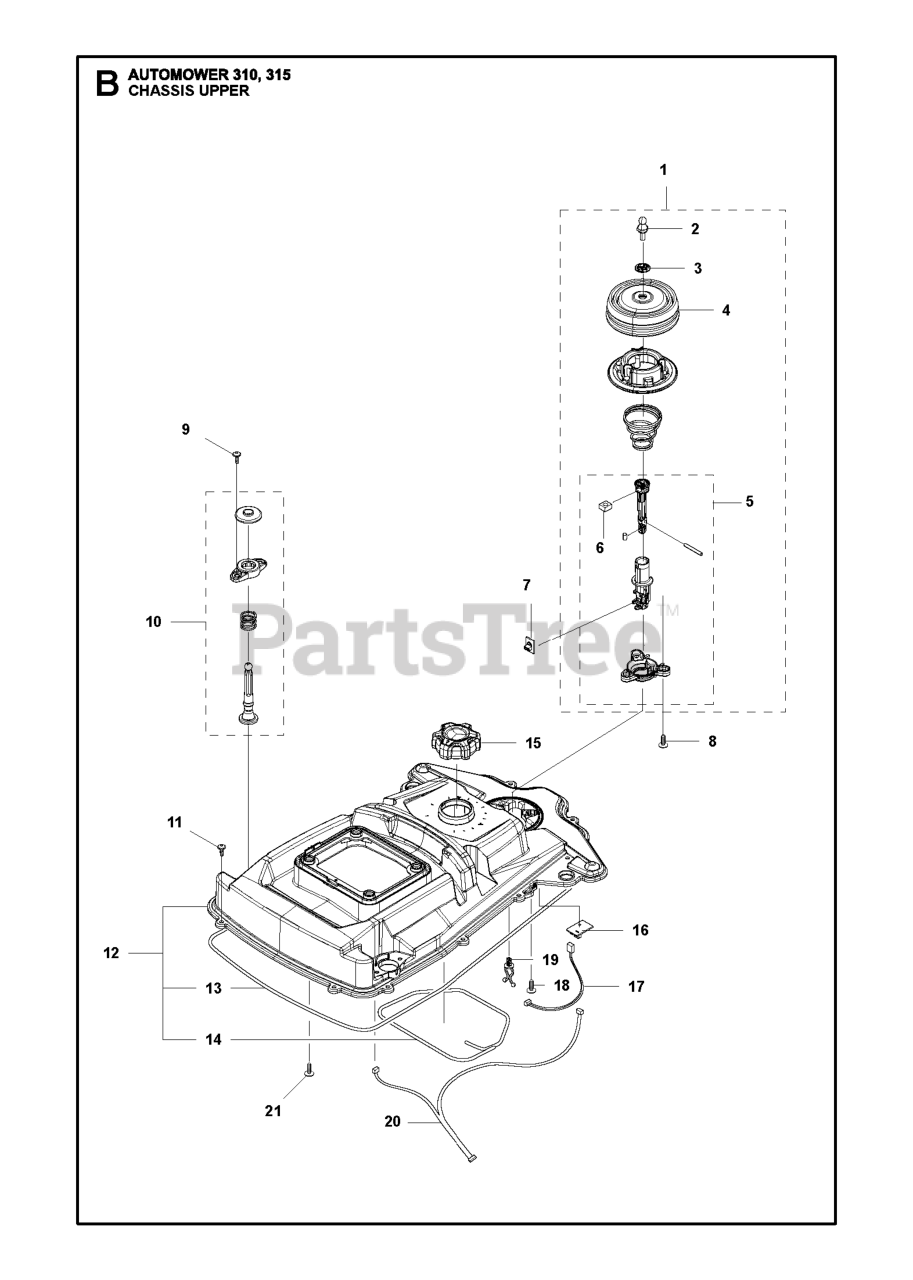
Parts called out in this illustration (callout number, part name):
1	WIRING ASSY TRIGGER HANDLE
1	JOYSTICK KIT
2	TRIGGER SWITCH IPX4
2	STUD SNAPLOC
3	KEY PAD 2 BUTTON TRIMMER DC (T
3	WASHER JOYSTICK
4	BELLOWS LIFT-COLLISION
5	WIRING ASSY FRONT GUARD
5	JOYSTICK KIT
6	CONTROL UNIT PMDC SAFE HEDGE T
6	NUT
7	GREASE TUBE Q8 RUYSDAEL WR2
7	PRINTED CIRCUIT ASSY PCBA LIFT
8	WIRING ASSY
8	SCREW 14MM
9	SWITCH KIT BATTERY HEDGETRIMME
9	SCREW ITXPANT
10	CONNECTOR BATTERY
10	JOYSTICK ASSY REAR
11	SCREW ITXPANT
12	CHASSIS KIT
13	SEALING STRIP P 15 CHASSI LOW
14	SEALING STRIP P15 UPPER
15	KNOB HEIGHT ADJUSTMENT
16	PRINTED CIRCUIT ASSY COLLISION
17	LOOM LIFT, COLLISION
18	SCREW ITXPANT
19	HOLDER TWIST LOCK
20	WIRING ASSY HMI
21	SCREW ITXPANT
